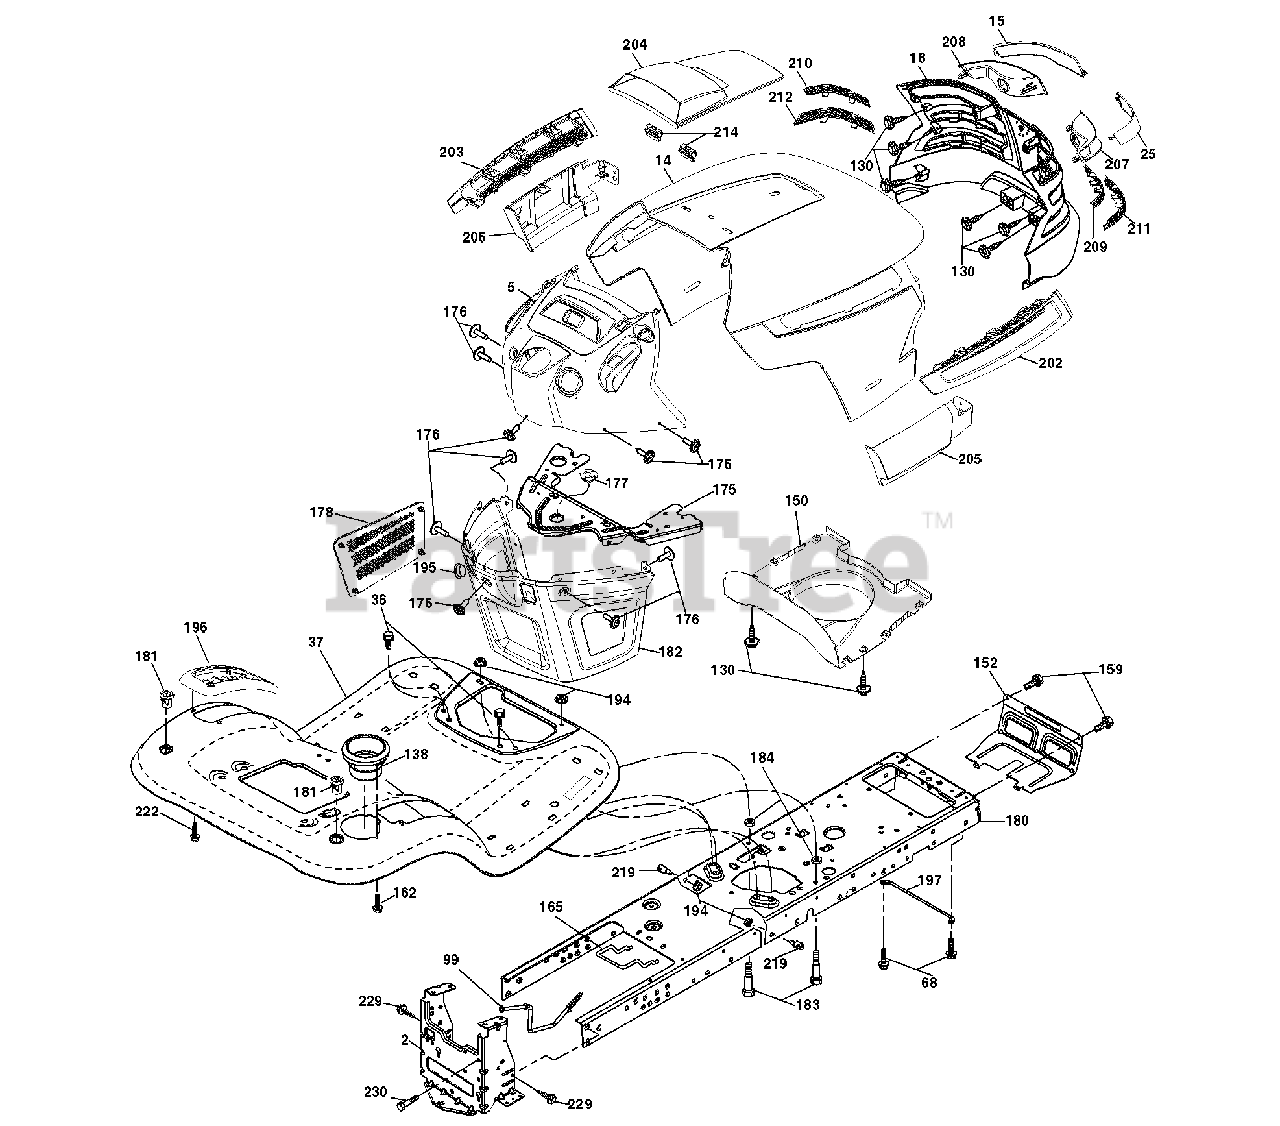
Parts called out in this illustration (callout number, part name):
5	Dash
14	Hood
18	Grille/Lens Asm.
36	Screw 5/16-18 x 3/4
37	Fender
68	Screw Thdrol 5/16-18 x 1/2
99	Rod Asm Bypass
130	Screw 10 x 3/4 Single Lead-Hex
138	Cupholder
152	Shield Browning
159	Screw Hexwsh Thdr 3/8-16 x 3/4
165	Support Tank Rear
175	Crossmember
176	Screw 10-24 x 5/8
177	Bushing Steering
178	Cargo Net Asm.
180	Chassis
181	Bushing Mtg. Fender Crgo
182	Dash Lower
183	Bolt Fin Hex 5/16-18 unc x 1-1/4
184	Spacer Fender
194	Nut Lock Hex Flange 5/16-18
195	Plug Hole Dash Lower
196	Console Asm. Deck Lift
197	Rod Pivot
202	Vent Side Hood RH
203	Vent Side Hood LH
204	Vent Top Hood
205	Skirt Hood Side RH
206	Skirt Hood Side LH
209	Insert Hex Top RH
210	Insert Hex Top Lh
211	Insert Hex Bottom RH
212	Insert Hex Bottom LH
214	Clip Retainer Tinner
219	Stud Fastner
222	Screw Thdrol 1/4-20 x 5/8
229	Screw 3/8-16 x 1
230	Bolt Shoulder 5/16-18
